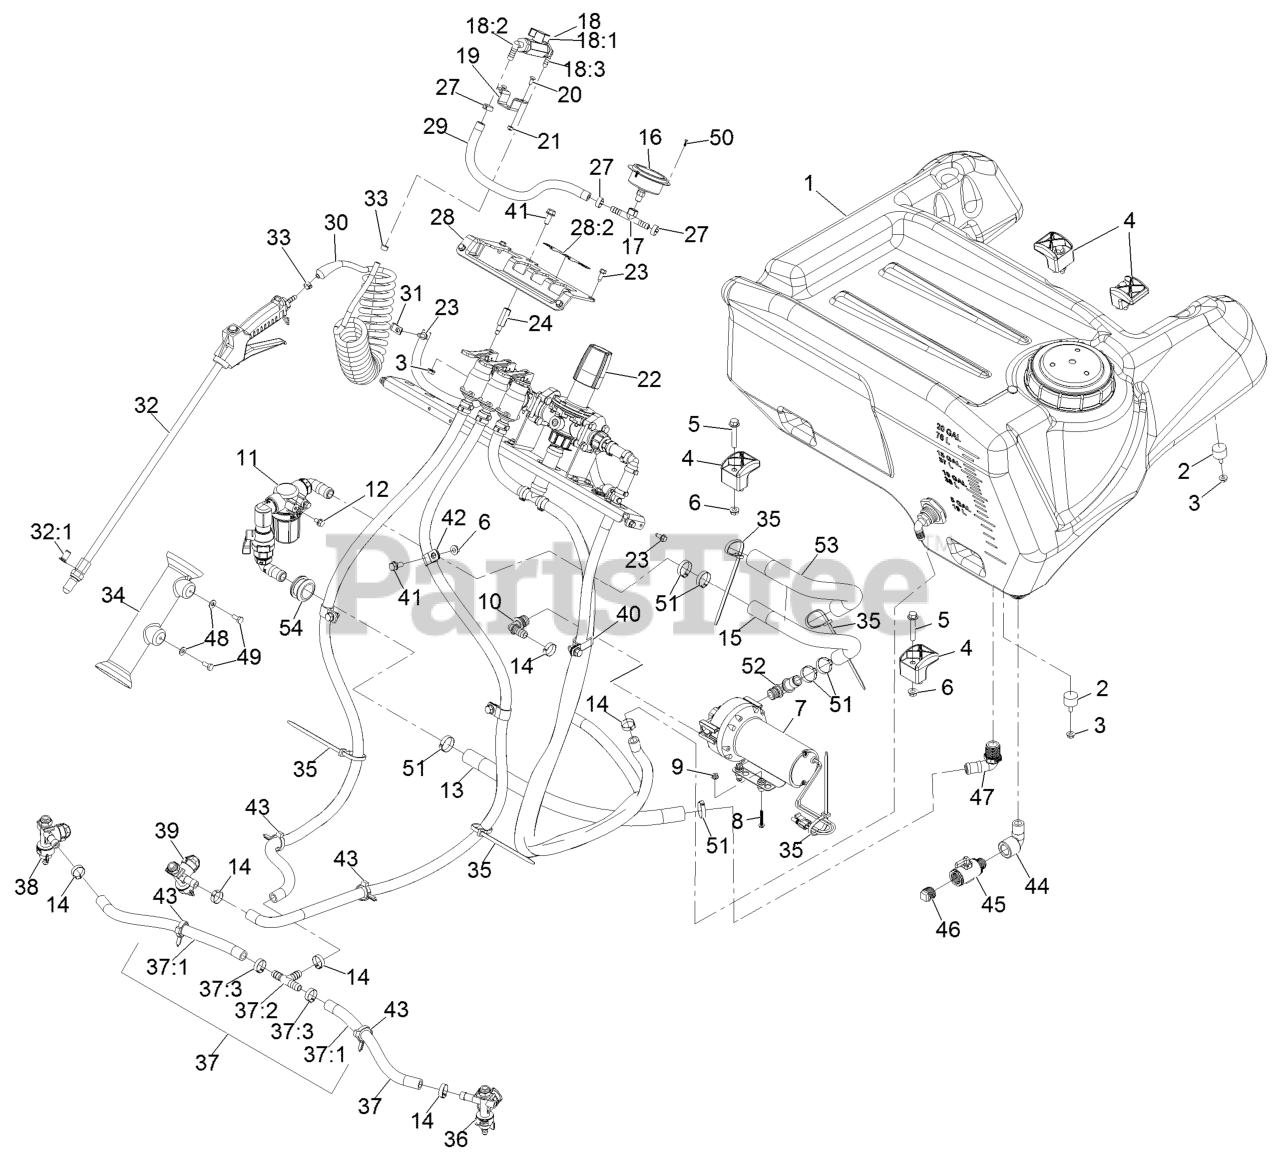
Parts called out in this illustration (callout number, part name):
1	TANK-SPRAYER
5	SCREW-HHF
7	PUMP-DIAPHRAGM, 3.8 GPM
8	SCREW-SHWH
10	FITTING-ELBOW, BARBED
11	STRAINER ASM
12	SCREW-HHF
13	HOSE-WATER
15	HOSE-WATER
16	GAUGE-PRESSURE
17	FITTING-TEE
18	Wand Control ASM
18:1	VALVE-BALL
18:2	FITTING-ELBOW-90
18:3	FITTING-ELBOW-90
19	BRACKET-VALVE
20	BOLT-CARR
21	NUT-LOCK, NI
22	Control Valve Manifold ASM
23	SCREW-HWH
24	SPACER-MOUNT, MANIFOLD
28	COVER-CONTROLS
28:2	DECAL-CONTROL, LEVER
29	HOSE-WATER, 3/8 PVC RED
30	HOSE-COILED
31	CLAMP-R
32	SPRAY WAND ASM
32:1	STRAINER-NOZZLE, 50M 5PSI
34	HOLDER-WAND
35	TIE-PLASTIC
36	LEFT NOZZLE SUB ASM
37	HOSE ASM
37:1	HOSE-WATER
37:2	FITTING-TEE
38	RIGHT NOZZLE SUB ASM
39	CENTER NOZZLE SUB ASM
41	SCREW-HHF
42	CLIP-LOOM
43	CLAMP-HOSE
44	ELBOW-90 DEG
45	MICROVALVE
47	ELBOW-HOSEBARB
48	WASHER-FLAT
49	SCREW-HH
50	SCREW-TAP
52	FITTING-ELBOW
53	SLEEVE-CORRUGATED, SPLIT
54	GROMMET
